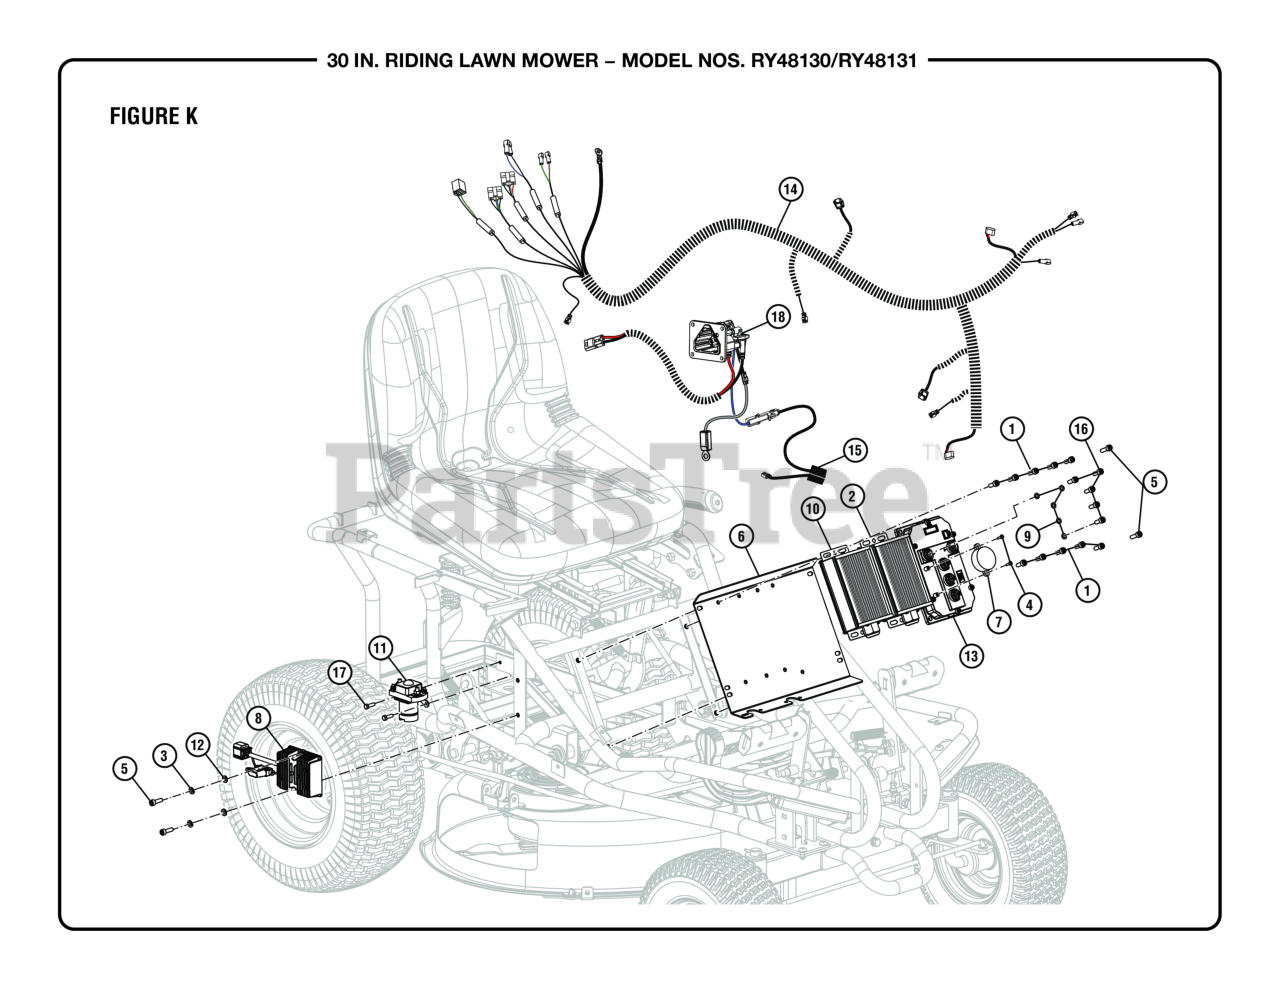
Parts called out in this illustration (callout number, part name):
1	Screw (M6 x 16 mm, Soc. Hd.)
2	Slave Deck Motor Controller
3	Spring Washer (M6) (For Deck Motor Controllers T & U)
4	Screw (M3 x 12 mm, Pan Hd.)
5	Screw (M6 x 20 mm, Soc. Hd.)
6	Controller Mounting Plate
7	Beeper (Q)
8	DC to DC Converter, ZTR
9	Washer (OD12 x ID5.3 x 1t) (For Main Relay G and Power Converter I)
10	Master Deck Motor Controller
11	Main Relay
12	Washer (OD12 x ID6.4 x 1.6t) (For Deck Motor Controllers T & U)
13	Drive Motor Controller
14	Main Wiring Harness
15	Charging Controller, ZTR
16	Bolt (Hex Hd.)
17	Screw (M4 x 12 mm, Cap Hd.)
18	Charger Receptacle
